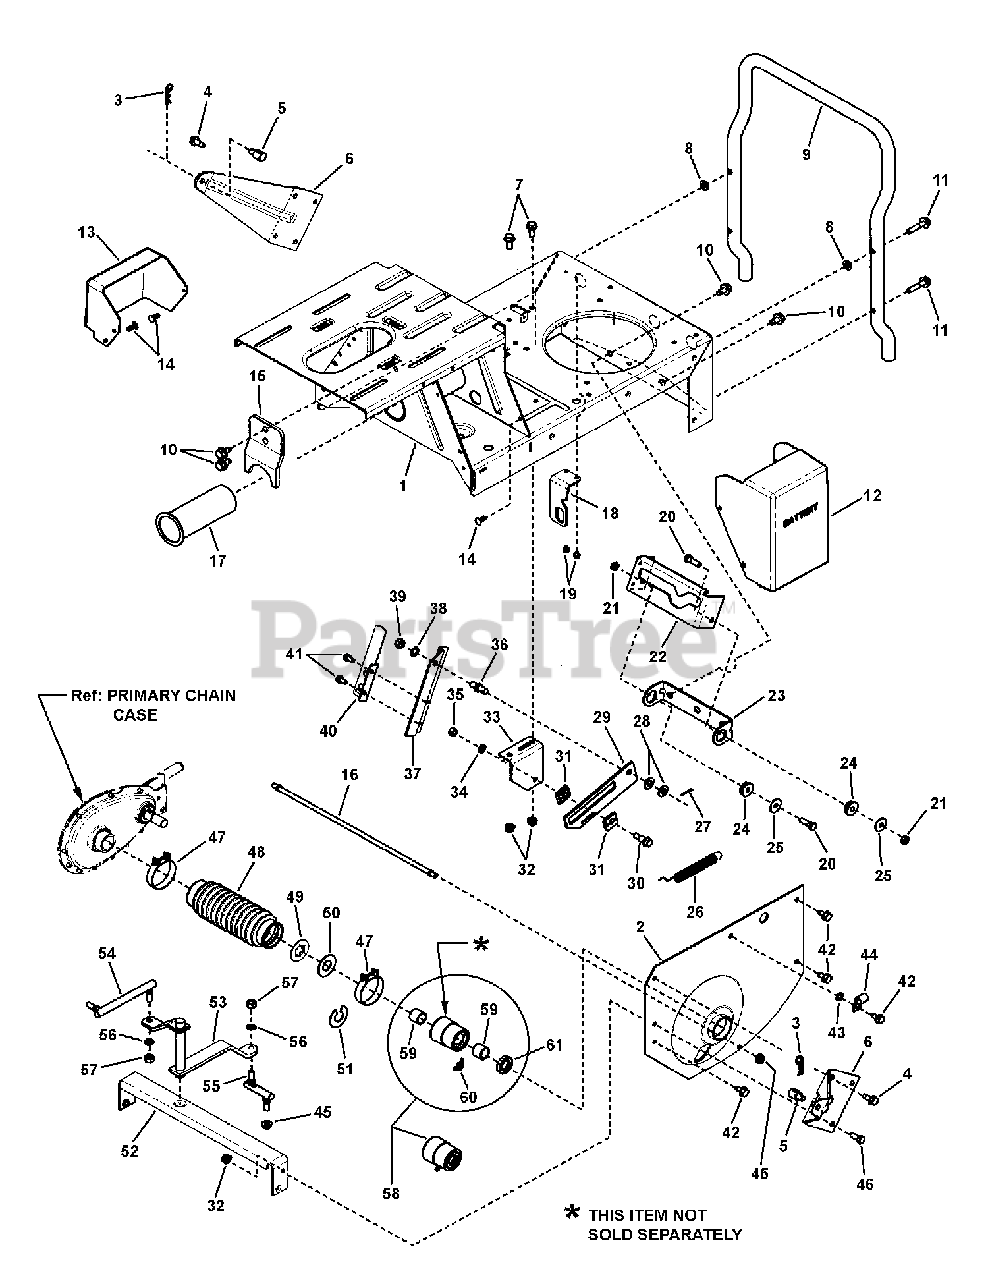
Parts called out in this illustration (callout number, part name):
1	WELDMENT, Main Case (Standard) (shown)
2	FENDER, Left Hand (1.628" I. D. Hole)
3	HAIR PIN, 3/32 x 1-1/2"
4	SCREW, 5/16-18 x 3/4" Hex Washer Self-Tap
5	SWIVEL, Adjustable, 5/16-18+.109 hole
6	WING, Rear
7	BOLT, 5/16-18 x 3/4" Hex Flange Lock, GR 5
8	WASHER, 11/32" Flat
9	BUMPER, (1-Piece)
10	SCREW, 3/8-16 x 5/8" Hex Washer Self-Tap
11	SCREW, 5/16-18 x 1-1/2" Hex Washer Self-Tap
12	COVER, Battery
13	COVER, Solenoid
14	FASTENER, 1/4" Ratchet
15	BRACKET, Belt Adjuster
16	TIE ROD, (5/16-24 thread- both ends)
17	BUSHING, Pivot
18	BRACKET, Switch
19	SCREW, #10-32 x 1/4" Hex Washer Self-Tap
20	SCREW, 5/16-24 x 1" Hex Head Cap, GR 5
21	NUT, 5/16-24 Hex Center Lock
22	LIFT, Yoke
23	COLLAR, Yoke
24	BEARING, Yoke
25	FENDER WASHER, 5/16"
26	SPRING, Clutch & Brake
27	PIN, 3/32 x 3/4" Cotter
28	WASHER, 3/8" Flat SAE
29	BRACKET, Slide
30	BOLT, 5/16-18 Shoulder
31	SLIDE HALF
32	NUT, 5/16-18 Hex Flange Lock, GR 5
33	BRACKET, Drive Support
34	WASHER, 5/16" Split Lock
35	NUT, 5/16-18 Hex, GR 5 or B
36	STUD, Clutch Link (3/8-24 thread)
37	ARM, Yoke
38	WASHER, 3/8" Internal Tooth Lock
39	NUT, 3/8-24 Hex, GR 5 or B
40	ASSEMBLY, Leaf Spring
41	SCREW, 1/4-20 x 1/2" Hex Washer Self-Tap
42	SCREW, 5/16-18 x 5/8" Hex Washer Self-Tap
43	WASHER, 5/16" Internal Tooth Lock
44	CLIP, Wire
45	NUT, 5/16-24 Flange Lock (Large)
46	SCREW, 5/16-18 x 3/4" Hex Head Cap, GR 5
47	BOOT CLAMP, 2"
48	BOOT, Rear Axle, Thick Flange
49	WASHER, Thrust, (Hex Flanged)
50	WASHER, Thrust, (.765" ID, 1.625" OD)(Nylon)
51	WASHER, Shim (Nylon, can make from 7011071)
52	CROSS BRACE
53	WELDMENT, Shift Arm
54	SHIFT LINK, Long (5/16-24 both ends)
55	SHIFT LINK, Short (5/16-24 thread)
56	WASHER, .32 x .58 x .08 Split Lock
57	NUT, 5/16-24 Hex, GR 5
58	ASSEMBLY, DX Bearing
59	BEARING, DX, 3/4" ID
60	FITTING, Lube, 45 Degree, 3/16" w/Hex (long shank)
61	SEAL, Axle (Dust/Grease)
